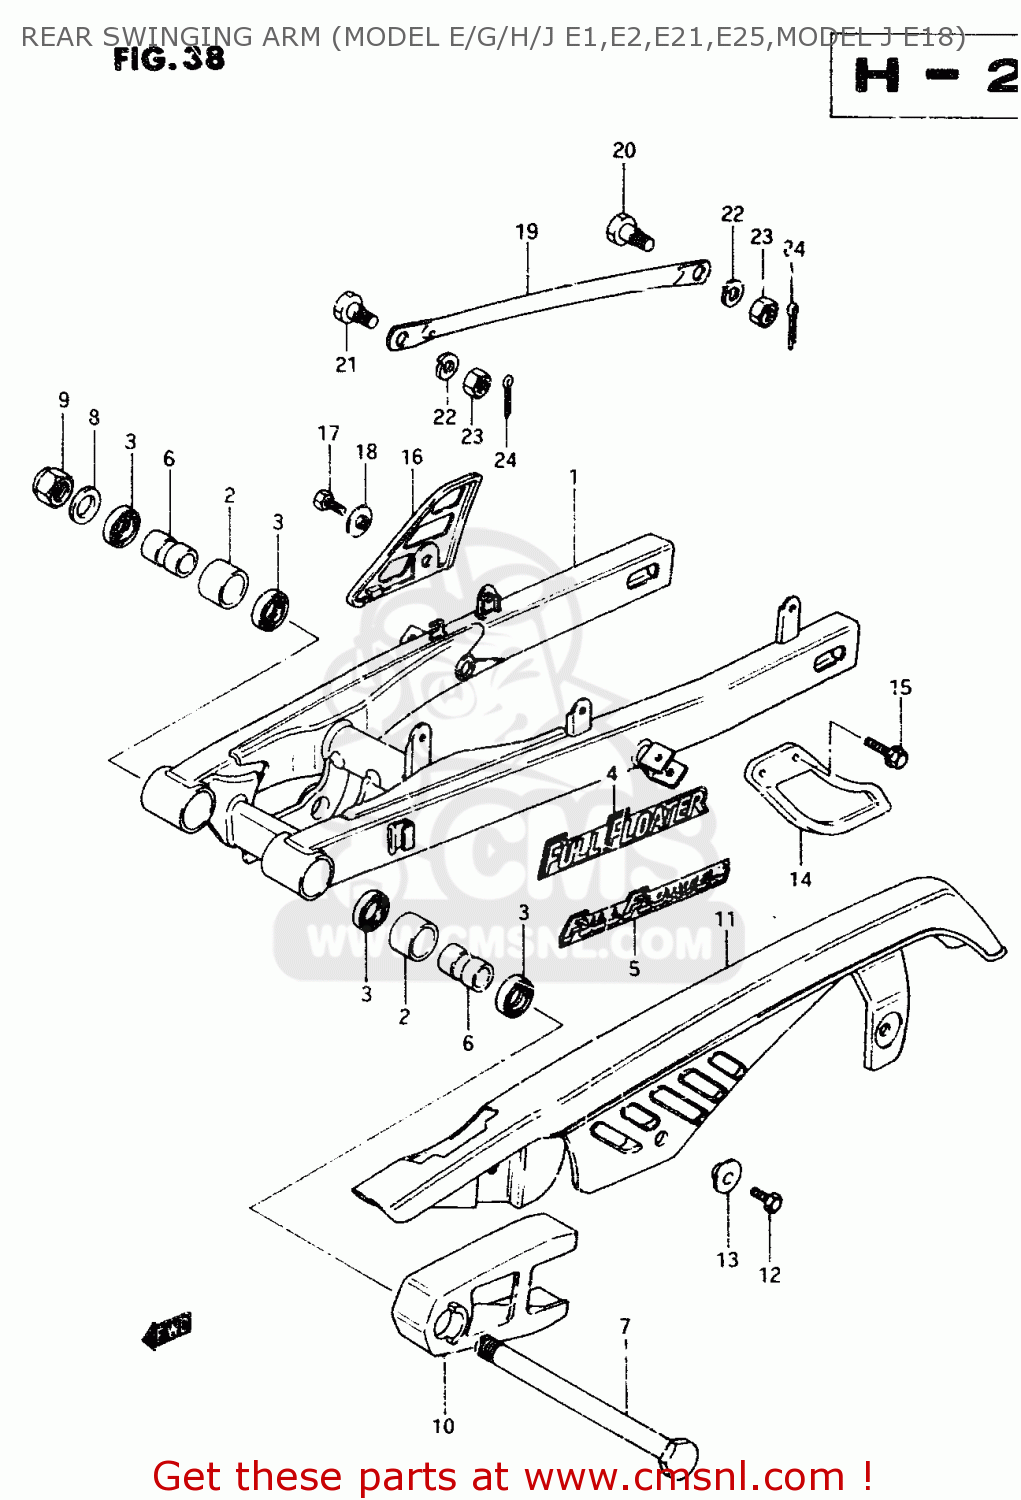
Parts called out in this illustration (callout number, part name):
1	SWINGING ARM ASSY, REAR (GOLD)
2	BUSHING,RR SWGARM PIVOT
3	OIL SEAL
4	EMBLEM
5	EMBLEM,SWING ARM
6	SPACER,RR SWINGING ARM PIVOT
7	SHAFT,RR
8	WASHER
9	NUT 14MM
10	BUFFER,CHAIN TOUCH DEFENCE
11	CASE,CHAIN
12	BOLT
13	WASHER
14	GUIDE,CHAIN
15	BOLT
16	GUARD, FOOT (BLACK)
17	BOLT
18	WASHER
19	TORQUE LINK,RR
20	BOLT(8X26.5)
21	BOLT(8X22)
22	LOCK WASHER
23	NUT
24	PIN 20X20
